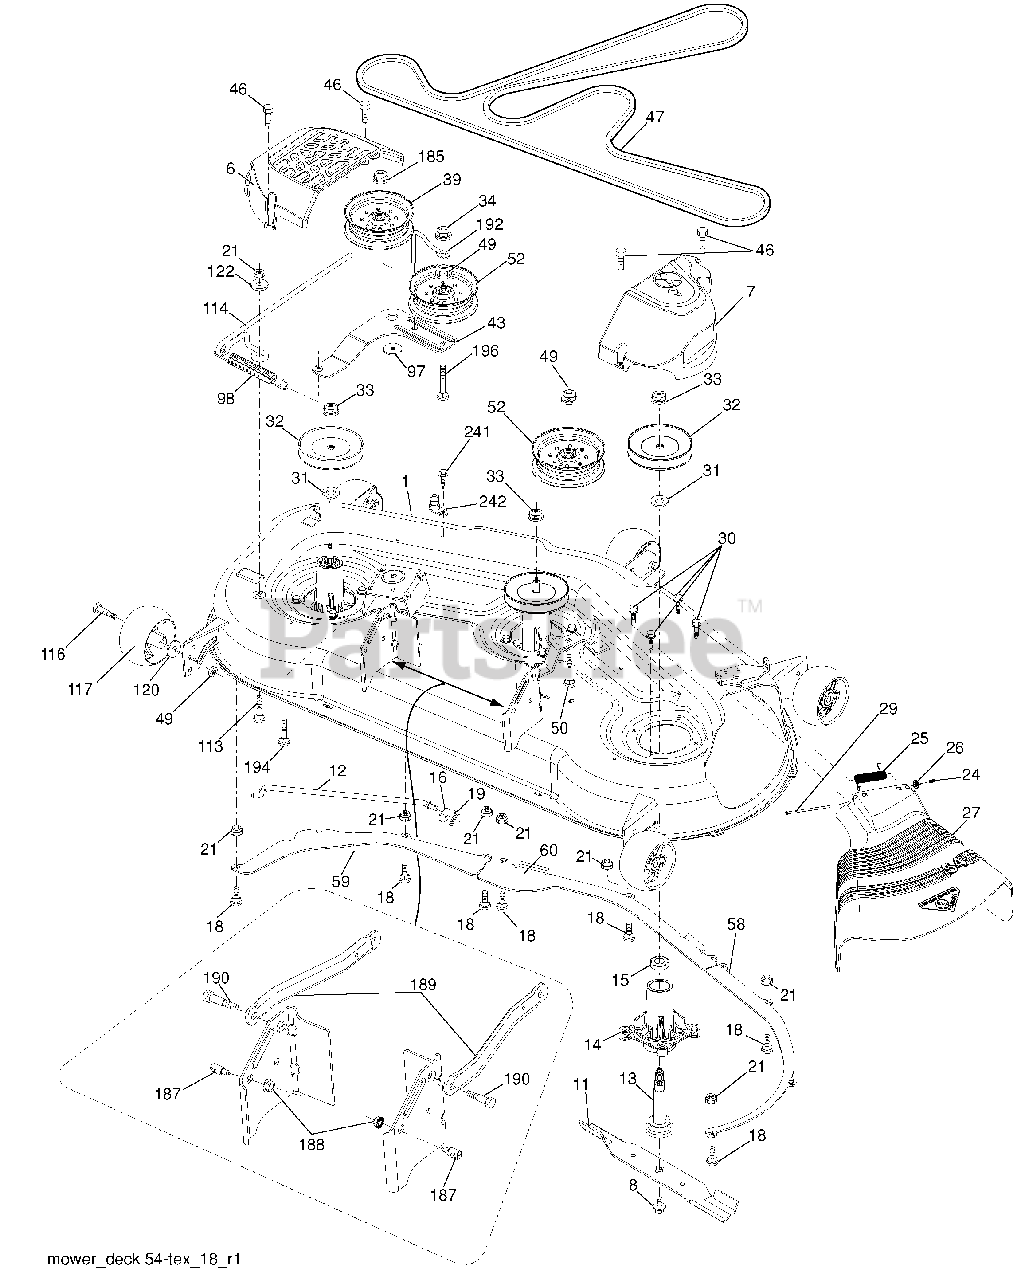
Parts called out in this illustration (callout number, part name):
1	Deck Weldment Mower
6	Cover Mandrel LH
7	Cover Mandrel RH
8	Bolt 7/16 Asm. Blade
11	Blade Bagging
12	Rod Anti Sway
13	Shaft Asm. w/Lower Bearing
14	Housing, Mandrel
15	Bearing, Ball, Mandrel
16	Washer 3/8
18	Bolt Carriage 5/16-18 x 5/8
19	Pin Cotter 5/16 Bowtie
21	Nut, Crownlock 5/16-18 unc
24	Cap Sleeve
25	Spring, Torsion
27	Deflector Shield
29	Rod, Hinge
30	Screw, Thdroll Washer Head
31	Washer, Spacer Mower Vented
32	Pulley, Mandrel
33	Nut, Flg. Top Lock
34	Nut Crownlock 3/8-16 unc
39	Pulley, Idler, 4.50
43	Arm, Idler
46	Screw, Thdroll. 1/4-20 x 5/8
47	Belt Deck Drive
49	Nut, Lock Flg. 3/8-16 unc
50	Bolt Rdhd Sqnk 3/8-16 unc x 2
52	Pulley Idler
58	Baffle Right
59	Baffle Left
60	Baffle Center
97	Washer Hardened
98	Spring Drive
113	Bolt Rdhd Sqnk 5/16-18 x 3/4
114	Rod Tension Relief
116	Bolt, Shoulder
117	Gauge Wheel
120	Washer 13/32 x 1-1/4 x 12 Ga.
122	Bushing Tension Relief
184	Nut Lock Hex Flange 5/16-18
185	Nut Lock Flange 7/16-14 Gr. 5
187	Stud Fastener w/"D" Anti-Rotation
189	Arm Susp. Mower Rear
190	Bolt Shoulder
192	Keeper Belt Idler
194	Bolt Carr Sqnk 7/16-24 x 2
196	Bolt Rdhd 3/8-16 x 2-1/2 Gr. 5
241	Screw TT #10-32.5. 3/8 Flange
242	Port Washout
